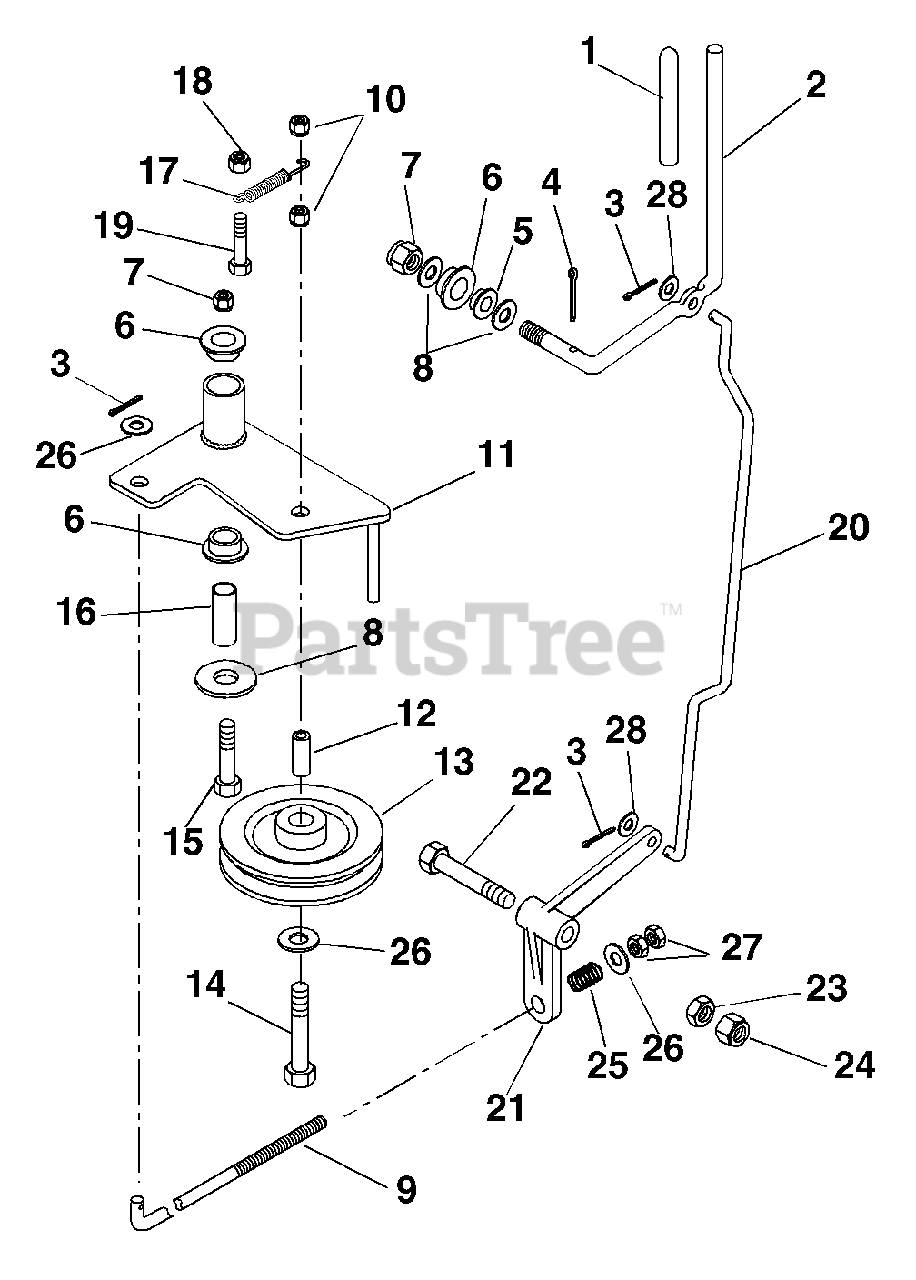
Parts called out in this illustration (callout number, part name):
1	GRIP,PTO LEVER
2	LVR,PTO ACTUATING
3	PIN-CTR .09X.75 EXTPRSQCT YWZ
4	@PIN-CTR .18X1.50 EXTPRSQCT YZ
5	BSHG-FLG .515X.750X.745X1.00NY
6	BSHG-FLG .762X1.0X.580X1.48 NY
7	@NUT-LK-CTR .50-13 YWZC
8	@WSHR-FL-STL.50X1.25X.083 YWZC
9	PTO LINK ROD, PRO-150
10	@NUT-LK-CTR .38-16 YWZC
11	DECLUTCH ARM - PRO PTO
12	SPACER .391 ID X .62 OD X 1.0
13	IDLER-PLY FLAT 3.25 X .38 X1.0
14	@BLT-HEX .38-16X3.50 GR5 YWZC
15	@BLT-HEX .50-13X3.25 GR5 YWZC
16	BUSHING FOR DECLUTCH ARM PIVOT
17	SG-TENS .095X.85X4.38 WLD25
18	@NUT-LK-CTR .31-18 YWZC
19	@BLT-HEX .31-18X1.25 GR5 YWZC
20	PTO LEVER LINK ROD, PRO 150
21	LVR,PTO CLUTCH
22	@BLT-HEX .50-13X2.50 GR5 YWZC
23	@NUT-HEX .50-13 YWZC
24	@NUT-LK-CTR .50-13 YWZC
25	SG-COMP .125X.78X1.00 YWZ
26	@WSHR-FL-STL.406X.812X.065 YWZ
27	@NUT-HEX .38-16 YWZC
28	@WSHR-FL-STL.344X.688X.065YWZC
